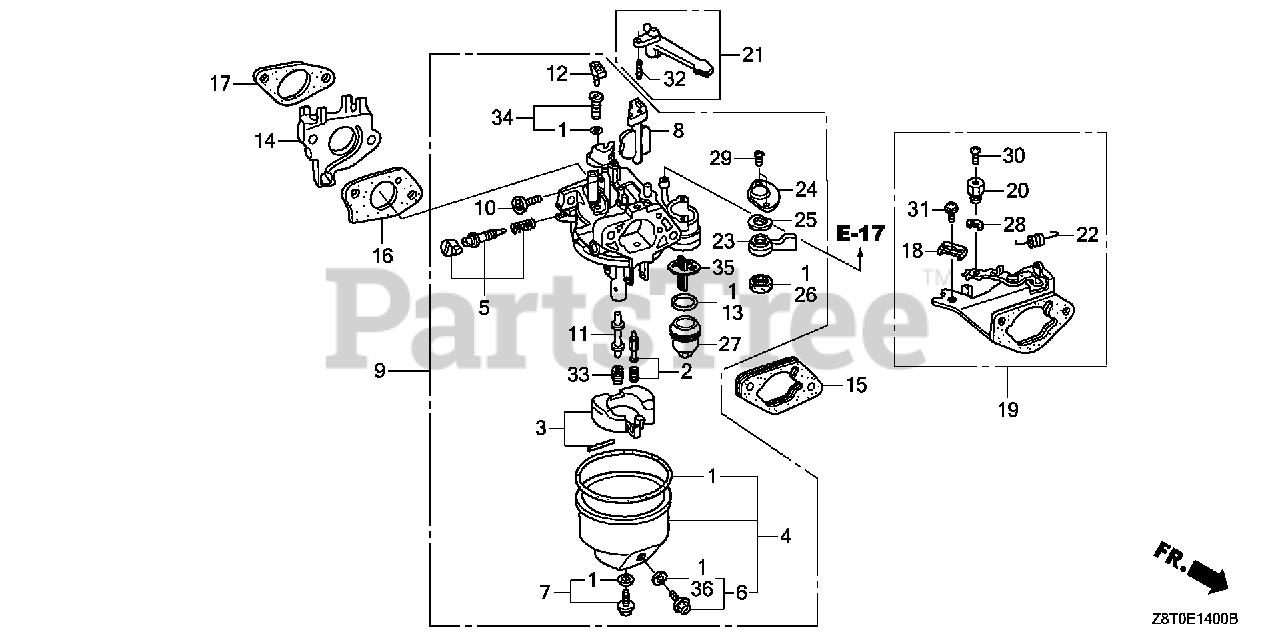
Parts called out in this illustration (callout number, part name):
1	GASKET SET (INCLUDES 16173-001-004)
2	VALVE SET, FLOAT
4	CHAMBER SET, FLOAT
5	SCREW SET, PILOT
6	SCREW SET, DRAIN
9	CARBURETOR ASSY. (BE80M A)
10	SCREW, THROTTLE STOP
11	NOZZLE, MAIN
12	COLLAR, SETTING
13	GASKET, FUEL STRAINER CUP
14	INSULATOR, CARBURETOR
15	SPACER, CARBURETOR
16	GASKET, CARBURETOR
17	GASKET, CARBURETOR INSULATOR
21	LEVER, CHOKE (STD)
23	LEVER, PETCOCK
24	PLATE, LEVER SETTING
25	SPRING, PETCOCK LEVER
26	GASKET, PETCOCK
27	CUP, FUEL STRAINER
29	SCREW, PAN (3X6)
32	PIN, SPRING (2X12)
33	JET, MAIN (#90)
33	JET, MAIN (#95)
33	JET, MAIN (#98)
34	JET SET, PILOT (#38)
35	FILTER, CUP
